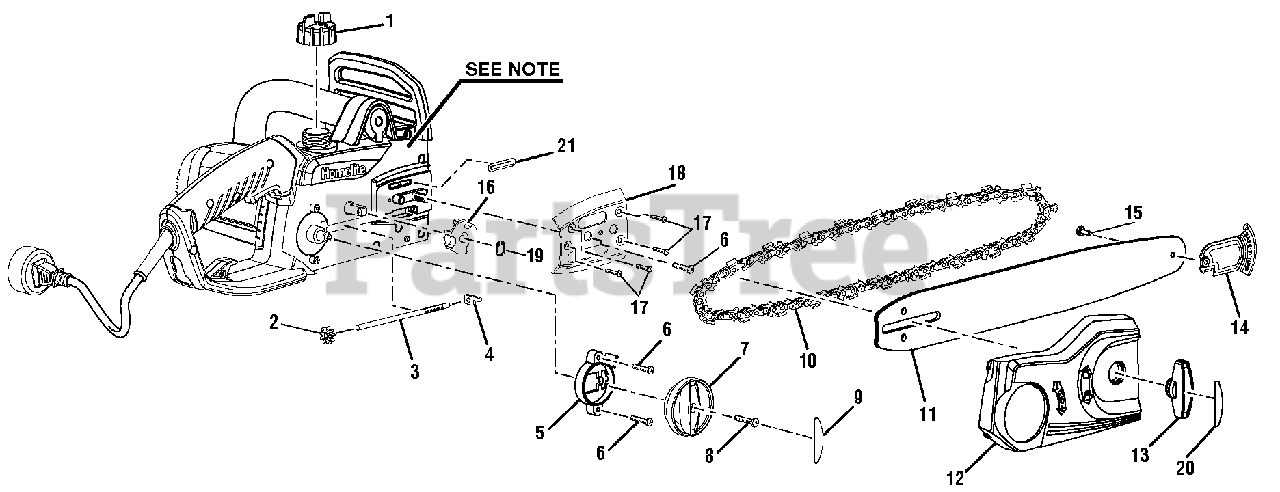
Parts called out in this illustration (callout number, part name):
1	Oil Reservoir Cap
2	Adjustment Gear
3	Adjustment Shaft
4	Adjustment Pin
5	Gear Cover
6	Screw (M4 x 8 mm)
7	Adjustment Knob
8	Screw (M4 x 10 mm)
10	Chain (.375 x 52 link, 14 in.)
11	Guide Bar (14 in. with SAFE-T-TIP)
12	Chain Cover Assembly
13	Chain Cover Lock Knob
14	SAFE-T-TIP
15	Screw w/Washer
17	Screw (M4 x 12 mm, Countersink)
18	Adjustment Pin Cover
19	Retaining Ring
21	O-Ring Seal
